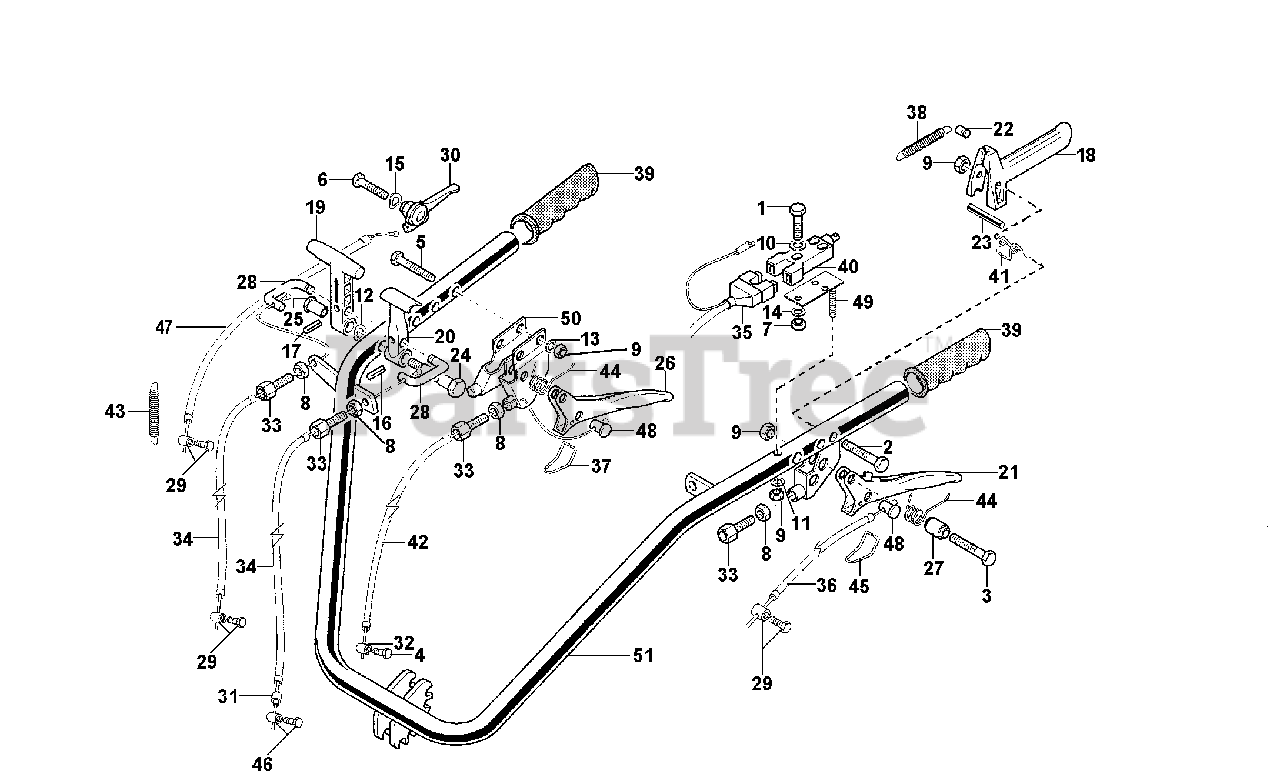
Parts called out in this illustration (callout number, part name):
1	SCREW, M4X25
2	SCREW, M6X45
3	SCREW, M6X25
4	SCREW, M6X16
5	SCREW, M6X35
6	SCREW, M8X35
9	NUT, SELF LOCKING, M6
10	FLAT WASHER, M4.3
11	WASHER, FLAT 6.4
13	WASHER, LOCK, M6.4
14	LOCK WASHER, M4.3
15	WASHER, LOCK, M8.4
16	PIN, LOCKING M4X20
17	PIN, LOCKING, M4X20
18	MOTOR STOP LEVER
19	REVERSER LEVER
20	LEVER DIFFERENTIAL LOCKING
21	CLUTCH LEVER
23	LEVER STOP FOR MOTOR STOP
25	DRILLED PIN
27	LEVER SPACER
29	CLAMP, CABLE
30	LEVER, ACCELERATOR
32	PIN, CABLE CLAMP
33	SCREW, ADJUSTING M8
34	CABLE, REVERSE
35	SWITCH WIRING HARNESS
36	CLUTCH CABLE
40	STOP SWITCH
41	MOTOR STOP LEVER SPRING
42	CABLE, BRAKE
43	SPRING, KOHLER
44	LEVER SPRING
46	CABLE CLAMP
47	THROTTLE CABLE
49	SWITCH PLATE
50	COUPLING FOR DOUBLE LEVER
